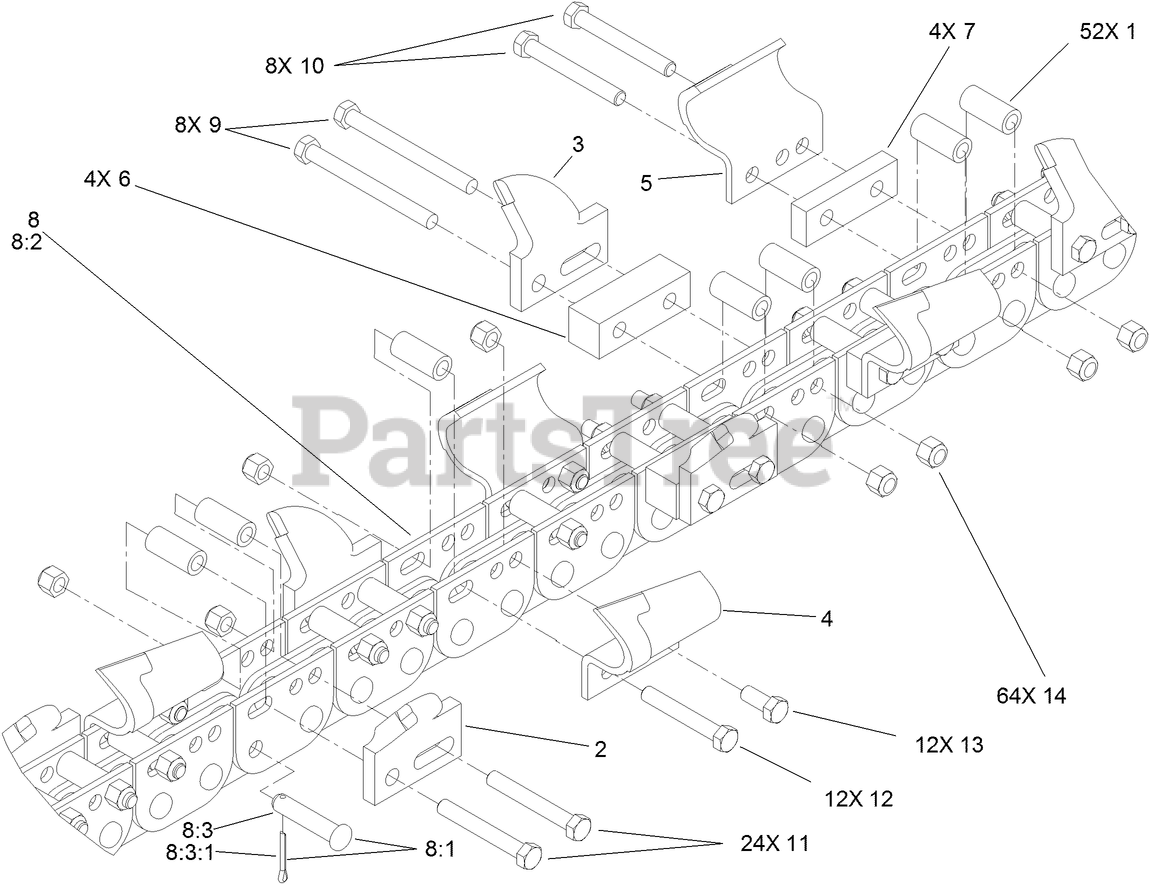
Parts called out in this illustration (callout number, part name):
1	SPACER-TUBE
2	TOOTH- ROCK, LH
3	TOOTH-ROCK, RH
4	TOOTH-SOIL, LH
5	TOOTH-SOIL, RH
6	SPACER-CUT, 6 INCH
7	SPACER-CUT, 5 INCH
8	CHAIN-BARE, 32 STATION
8:1	PIN-CONNECTING
8:2	LINK REPAIR KIT
8:3	PIN-CONNECTING (61MM)
8:3:1	PIN-COTTER
9	SCREW-HH
10	SCREW-HH
11	SCREW-HH
12	SCREW-HH
14	NUT-HEX
